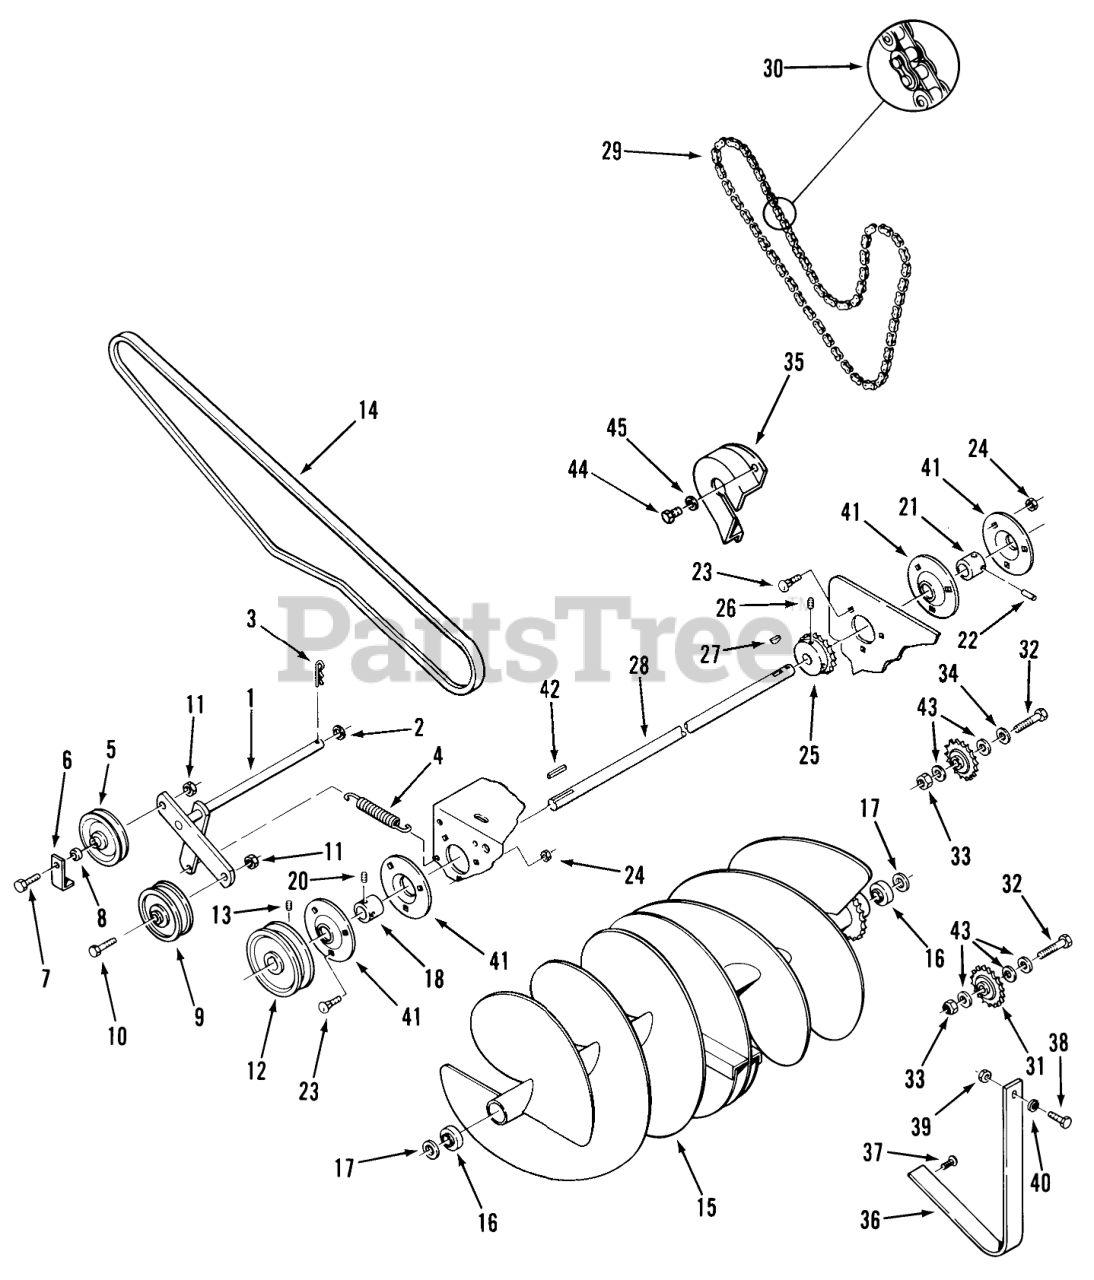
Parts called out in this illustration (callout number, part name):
1	ASSY IDLER ARM R
2	Washer
3	Hairpin
4	SPRING R
5	PULLEY-IDLER
6	Spacer
7	Bolt
8	SPACER
9	Idler Pulley
10	BOLT
11	Nut
12	Pulley
13	Set Screw
14	BELT DRIVE
14	V-BELT
15	Auger
16	BEARING-BALL
17	Washer
18	BALL BEARING
20	SET SCREW
21	LUTCO BALL BEARING
22	PIN-ROLL, SPIROL
23	Bolt
24	Nut
25	SPROCKET
26	SCREW-SET
27	KEY-WOODRUFF
28	SHAFT
29	CHAIN
30	MASTER LINK CHAIN
31	Idler Sprocket
32	H H C S
33	Eslok Nut
34	SPACER
35	GUARD-CHAIN
36	Guard
37	SCREW
38	H H C S
39	Nut 1/4-20
40	WASHER
41	FLANGE
42	KEY-STRAIGHT
43	Washer
44	Bolt
